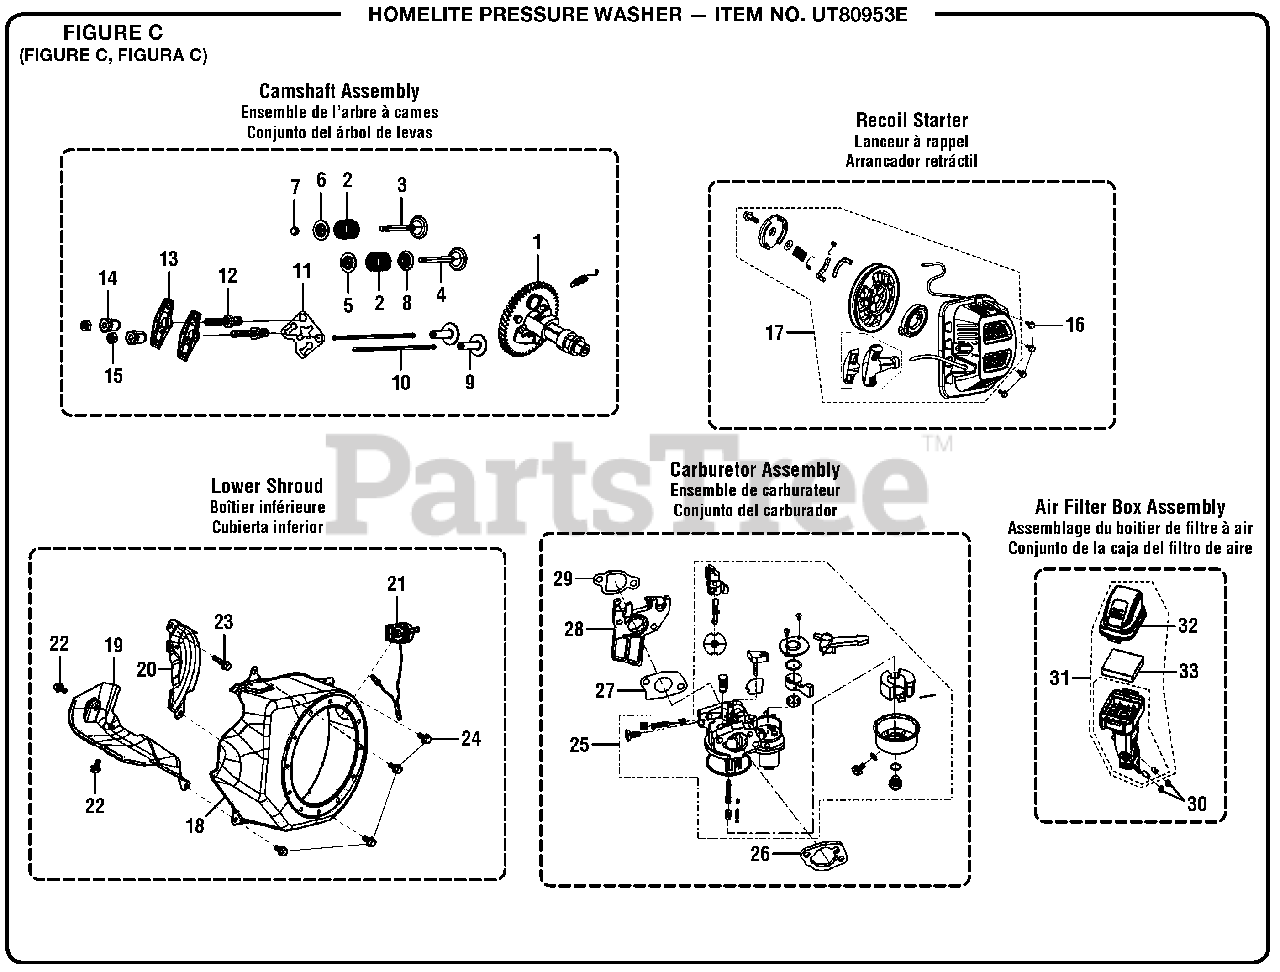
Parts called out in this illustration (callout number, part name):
1	Camshaft Assembly
5	Valve Spring Seat
6	Exhaust Valve Retainer
11	Stop Plate Assembly
12	Valve Adjusting Bolt
14	Valve Adjusting Nut
17	Recoil Starter Assembly
18	Shroud
19	Cylinder Body Shroud
21	Stop Engine Switch Assembly
25	Carburetor Assembly
26	Air Cleaner Gasket
27	Carburetor Gasket
28	Carburetor Insulator Plate
29	Carburetor Insulator Gasket
32	Air Cleaner Cover
33	Air Cleaner Element
